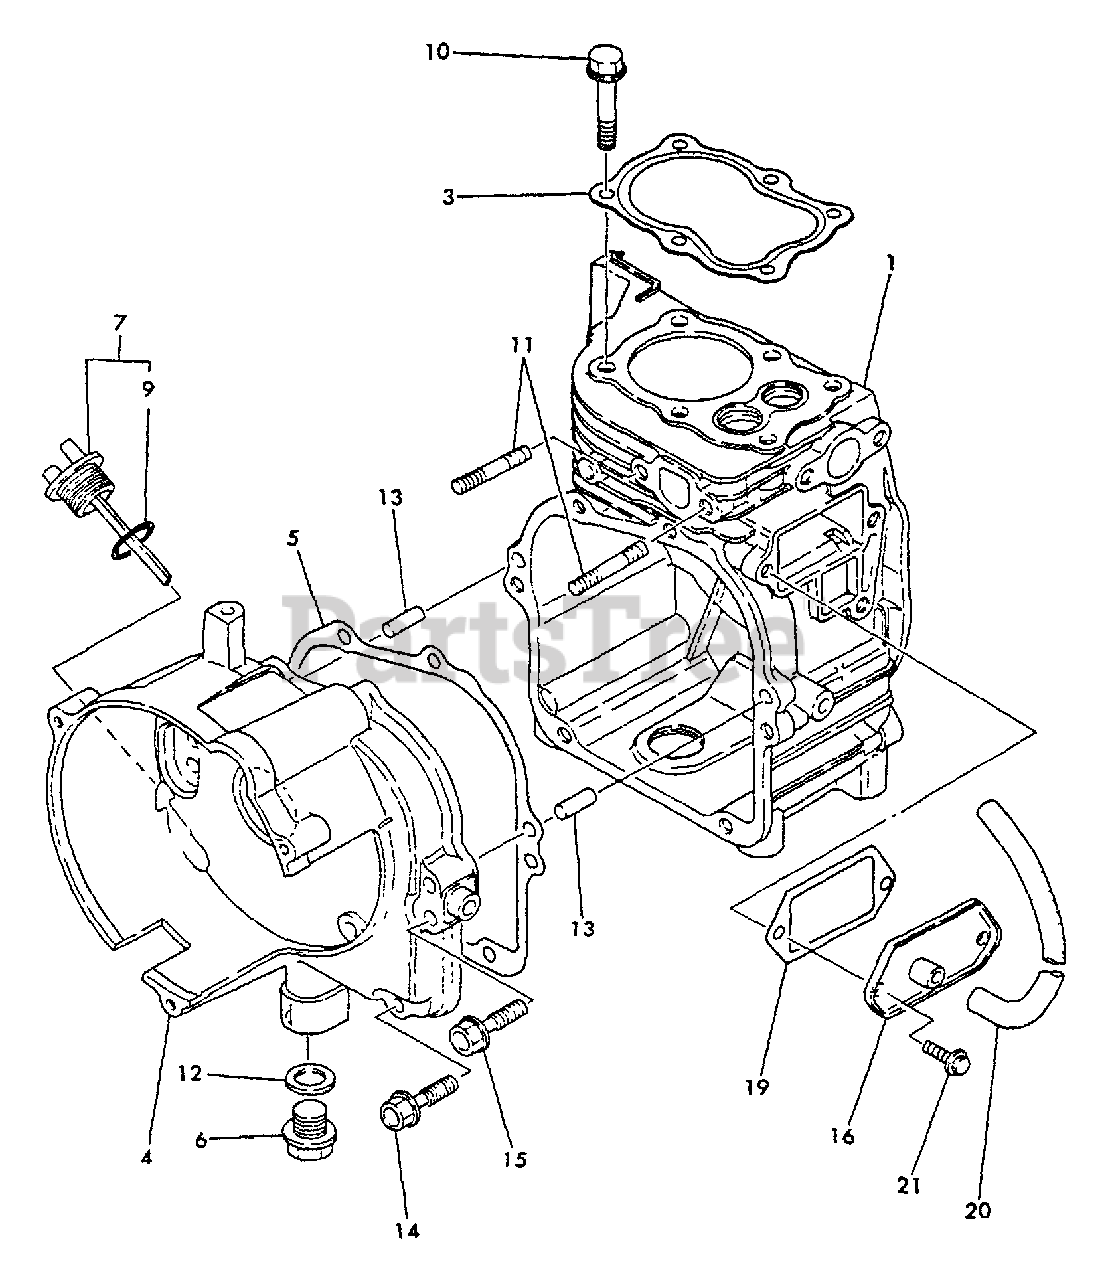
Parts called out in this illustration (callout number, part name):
1	CYLINDER BLOCK SET
3	GASKET, CYLINDER
4	COVER, CRANKCASE
5	GASKET, CRANKCASE
6	PLUG, DRAIN
7	CAP, OIL
9	O-RING 1A P-15.0
10	BOLT - 6×35
11	BOLT - 6×16
12	GASKET
13	PARALLEL PIN 6×16
14	BOLT - 6×30
15	BOLT - 6×30
16	BREATHER
19	GASKET, TAPPET
20	PIPE, BREATHER
21	BOLT - 6×8 -- PLATED
